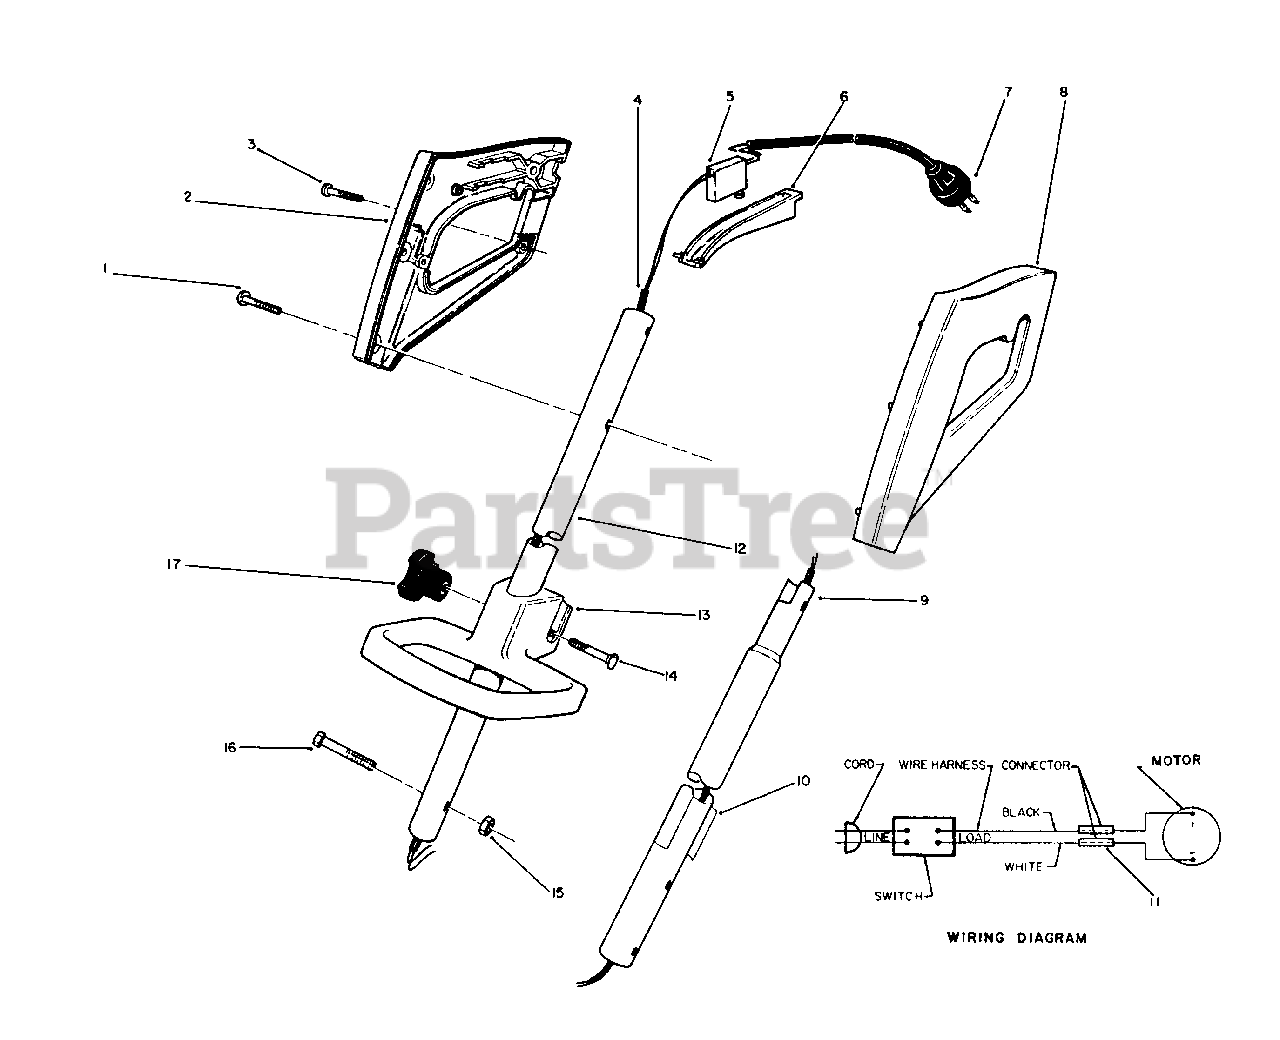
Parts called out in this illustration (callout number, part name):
1	Hex Hd. Capscrew
2	Grip-Hand R.H.
3	Pan Hd. Screw
4	Wire Harness Assembly
5	Switch
6	Bar-Switch
7	Cord-Power
8	Grip-Hand L.H.
9	Tube-Lower
10	Decal-Serial No. Replacement
11	Connector
12	Tube-Upper
13	Handle Assembly
14	Carriage Bolt
16	Hex Hd. Capscrew
17	Knob-Adjustable Handle
